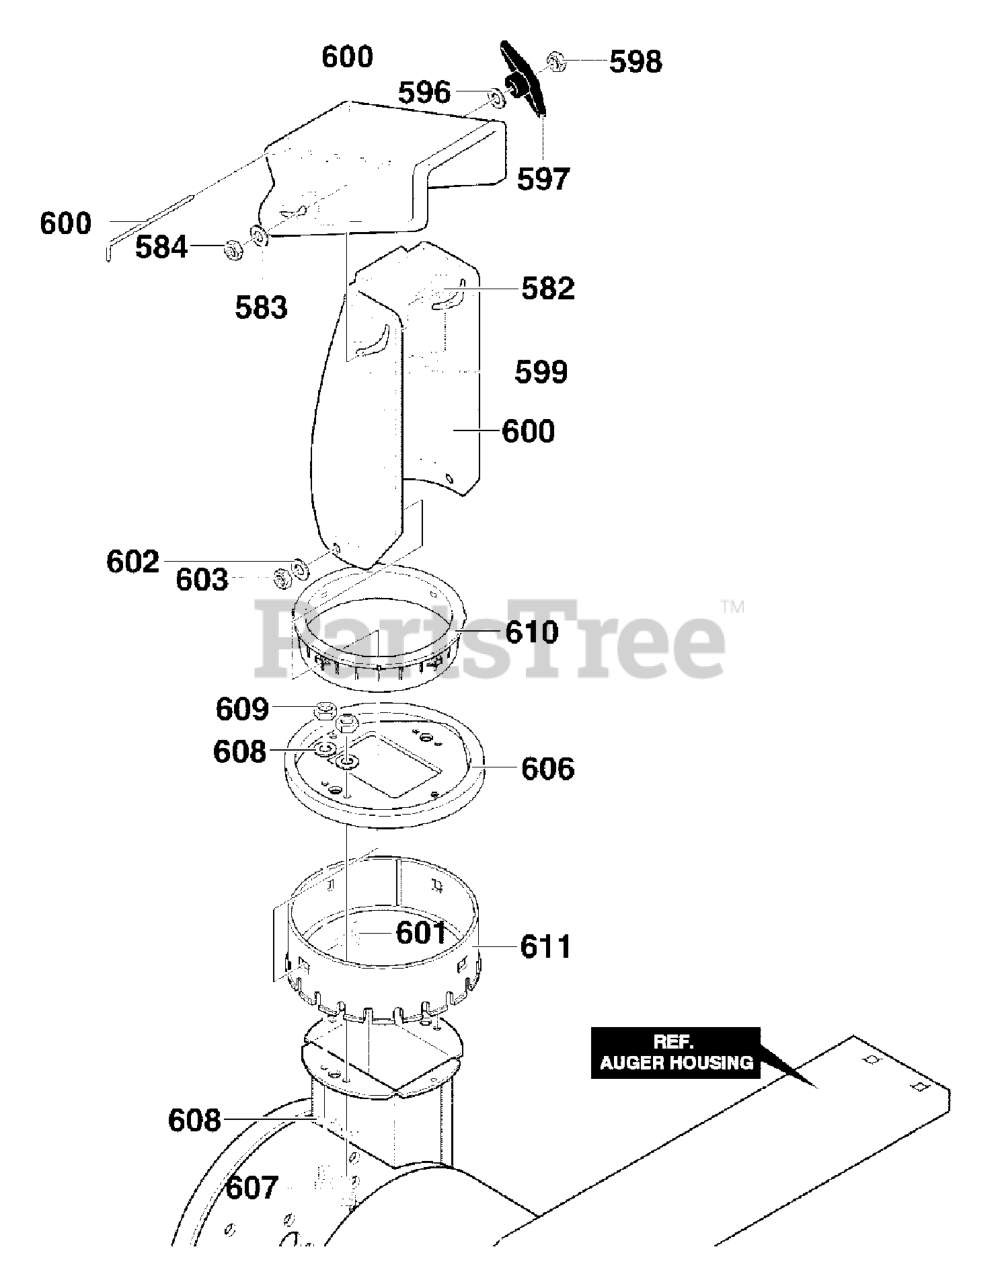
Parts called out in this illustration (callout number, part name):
582	SCREW, 5/16-18 x 0.75
583	WASHER, FLAT .349X.69X.066
584	NUT, 5/16-18 REGHEXCTRLK
596	WASHER, FLAT .349X.69X.066
597	KNOB, T 3.00
598	NUT, 5/16-18 REGHEX
599	BOLT, 5/16-18X1.25 CARR.
600	CHUTE ASSEMBLY
601	BOLT, 5/16-18 X1.00
602	WASHER, FLAT .349 X .69 X .066
603	NUT, 5/16-18 HEXNYL
606	CHUTE COLLAR
607	SCREW, 1/4-20 X .75
608	WASHER, FLAT .281X.63X.065
609	NUT, 1/4-20 HEX NYLOCK
610	RETAINER RING INNER
611	RETAINER RING OUTER
